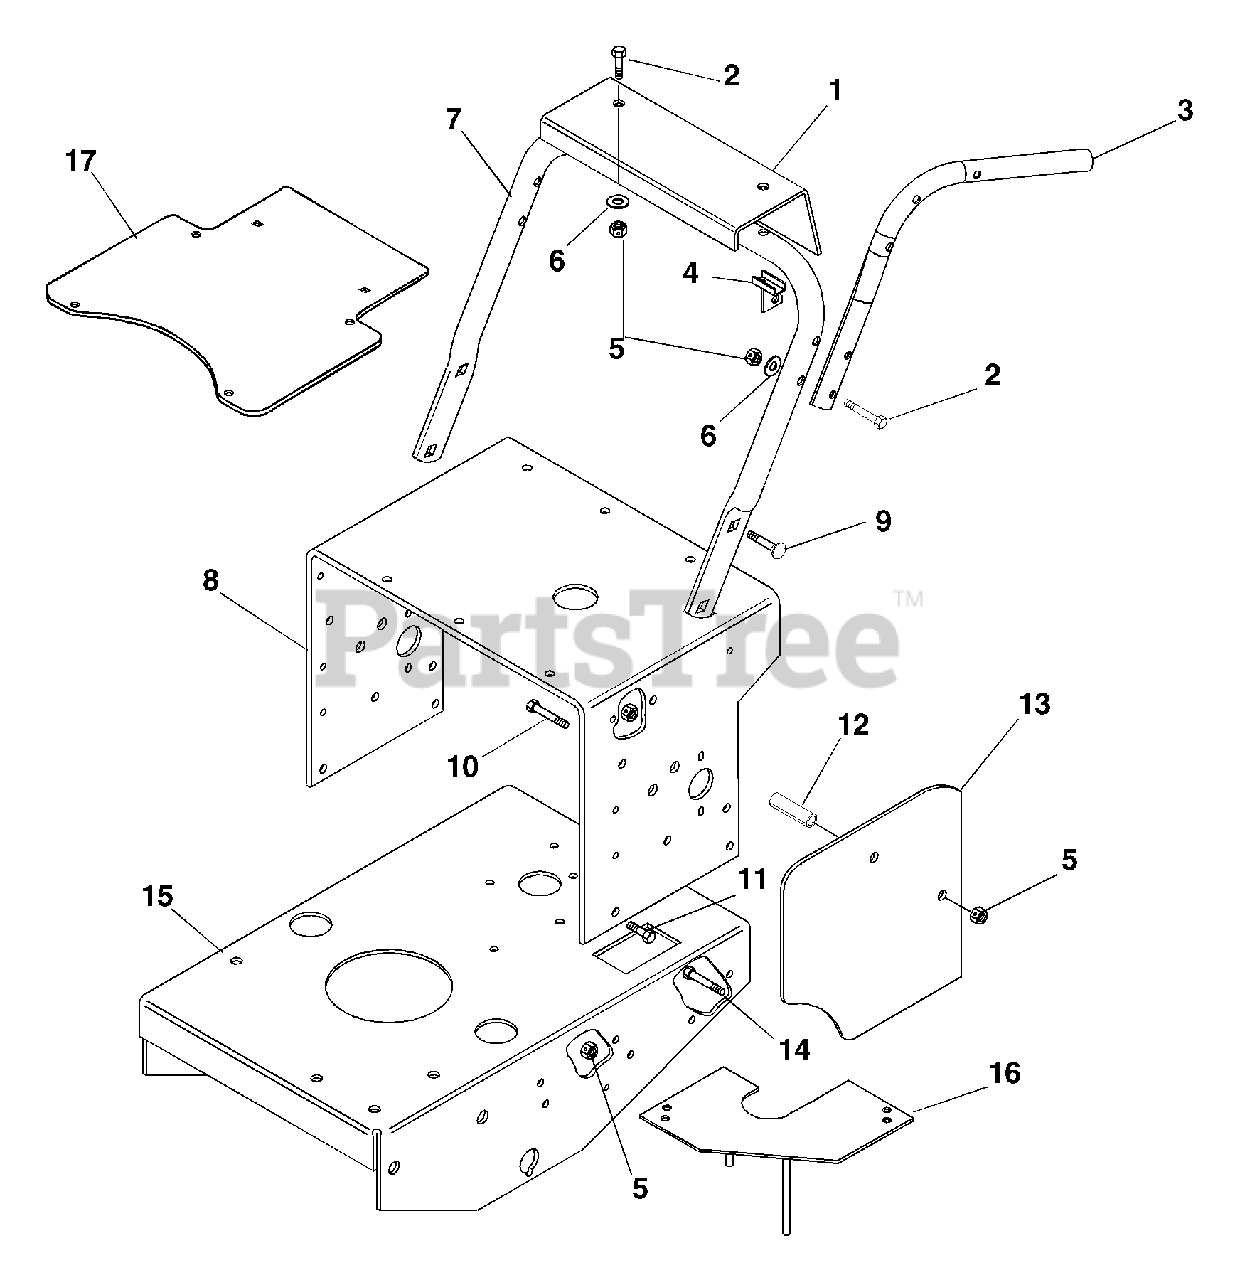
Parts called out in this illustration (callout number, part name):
1	Panel, Instrument
2	Bolt-Hex .38-16 x 2.00 Grade 5
3	Handlebar Left Hand
3	Handlebar Right Hand
4	PTO Lever Mounting Bracket
5	Nut-Locking-Center .375-16
6	Washer-Flat-Steel .406 x .812 x .065
7	Lower Handlebar-Pro 100
8	Pro-150 Top Frame
9	Bolt-Round Head Square Neck .38-16 x 1.0
10	Bolt-Hex .38-16 x 4.00
11	Bolt-Hex .38-16 x 1.00 Grade 5
12	Bushing-Spacer 3.25 x 3/8 ID x 5/8 OD
13	Guard-Drive Pro-100 Side Cover
14	Bolt-Hex.38-16 x 1.50 Grade 5
15	Pro-150 Main Frame
16	Belt Brake Finger-Deck Clutch
17	Plate, Mount
